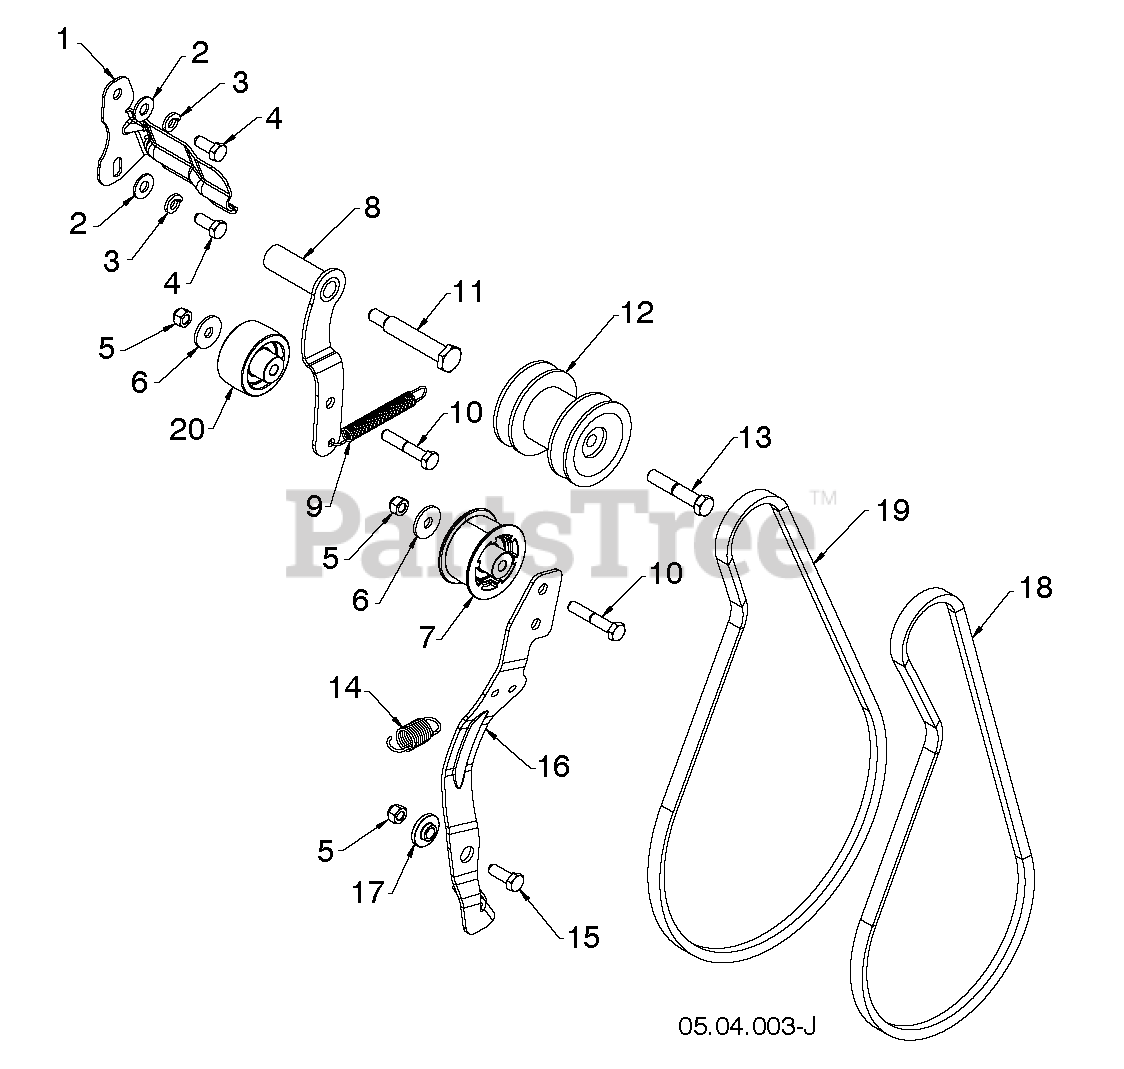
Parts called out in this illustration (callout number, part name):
1	BRACKET.BELT.KEEPER.004.BZP
2	WASHER M
3	LOCKWASHER
4	SCREW 5/16-24 X .75 GR5
5	NUT.71038.31-18.HEX.NYLOCK
6	STEEL WASHER
7	Idler Pulley, 2.00 W Spa
8	Drive Weldment Idler Arm, Hot 008
9	Idler Arm Return Spring
10	BOLT, HEX 5/16-18X1-3/4
11	Hex Head Shoulder Bolt, 5/16-24 X 2.25
13	BOLT.BLADE
14	Impeller Idler Arm Return Spring
16	Impeller Idler Arm Bracket
17	BUSHING, IDLER PIVOT
18	High Crank Impeller Belt
19	Drive Belt, Hi-Crank
20	Flange Idler Pulley, 2 O/Spacer
